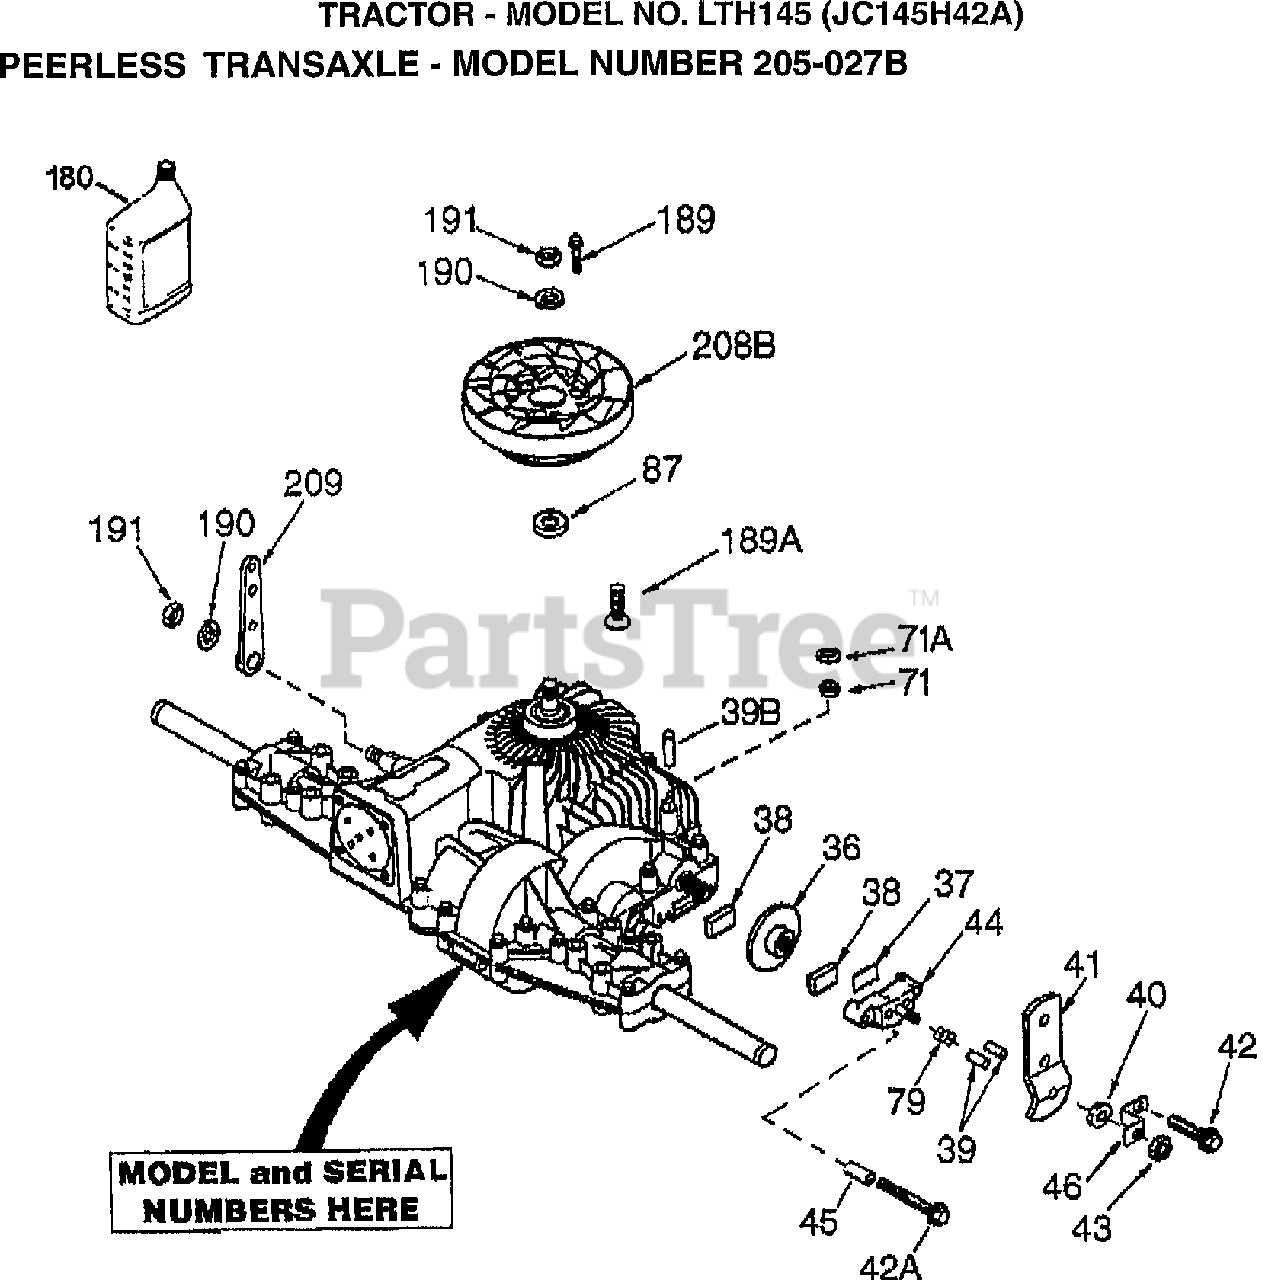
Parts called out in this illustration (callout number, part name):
37	PLATE BRAKE PAD
41B	BRAKE LEVER
42	SCREW, 1/4-20 X 1-1/4
42A	SCREW, 1/4-20 X 2-1/4
43	LOCKNUT 5/16-24
44	HOLDER BRAKE PAD
46	BRAKE LEVER BRACKET
71	SEAL SQUARE CUT
85	OIL FILL PLUG
180	GEAR OIL 80W90
189	DRIVE SCREW
208B	FAN/COUPLING
209	CONTROL LEVER
